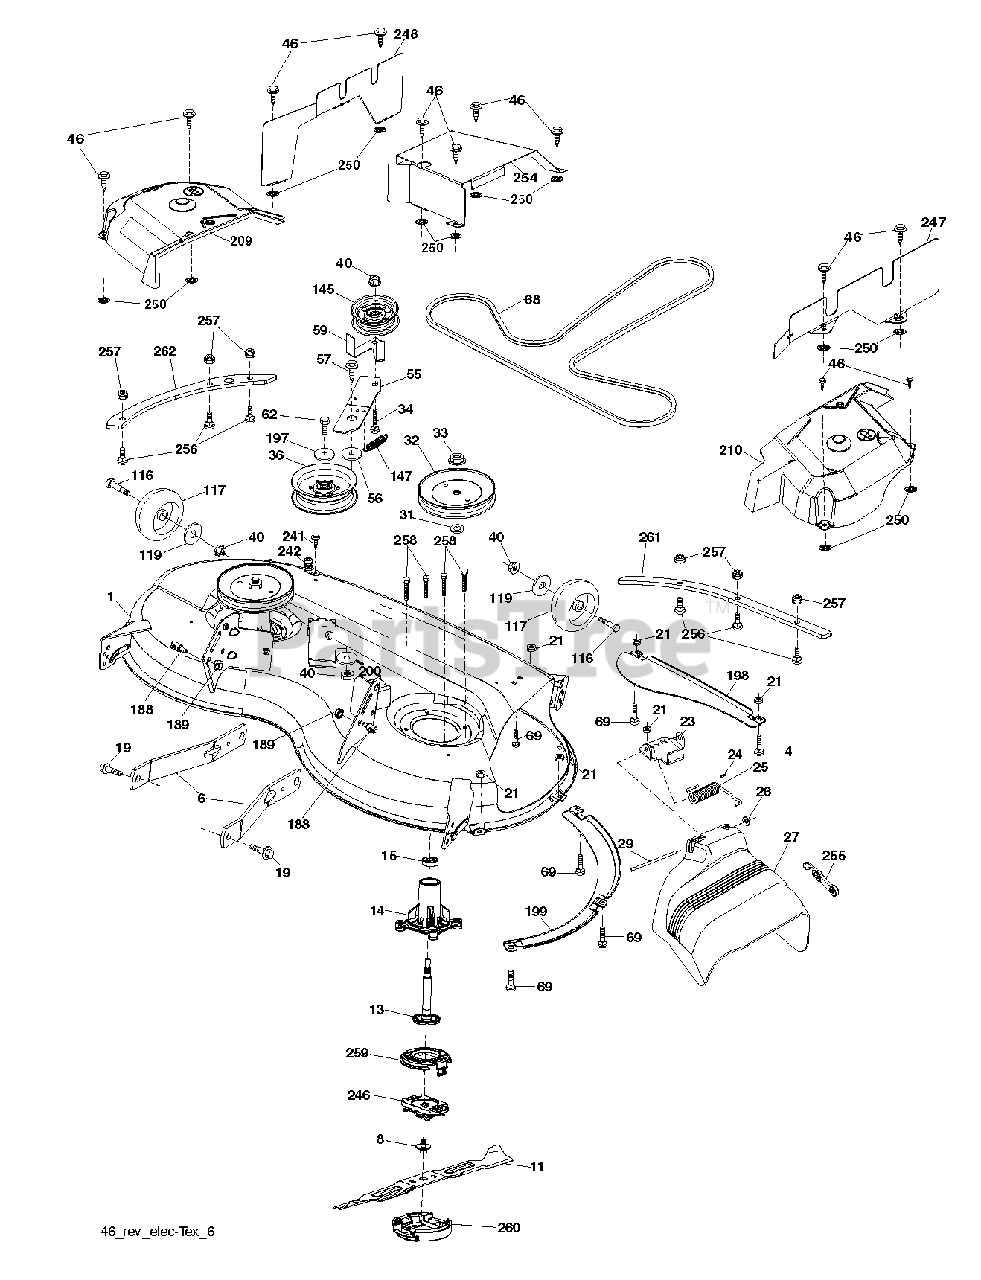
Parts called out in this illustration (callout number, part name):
1	HOUSING 46 WELDMENT TTR X498 G
4	BOLT
6	ARM.SUSPENSION.MOWER.R
8	BOLT.WASHER.ASM.7/16-2
11	BLADE.REVOLTION.46"BAGER.PT43
13	SHAFT ASM.REV.TALL.N/GREASEBL
14	HOUSING.MANDREL.REV.TALL.N/GRS
19	BOLT.SHOULDER
21	LOCKNUT
23	BRKT.DEFLECTOR.38"2005+
24	CAP-SLEEVE LT
25	SPRING.TORSION.DEFLECT
26	NUT PUSH M
27	SHIELD SUBASM DEFLECTOR 46 FRE
29	ROD.HINGE
31	WASHER.SPACER.MANDREL
32	PULLEY.MANDREL.5.438.PD
33	NUT.FLANGE.LOCK.TOP
34	BOLT.3/8-16X1.50
36	PULLEY.IDLER.2006
40	NUT LOCK FLG 3/8-16 UNC
46	SCREW.1/4-20X5/8
56	SPACER.RETAINER
57	SCREW 3/8-16X1
59	GUARD, BELT
62	BOLT-HEX EAK
68	V-BELT
69	BOLT
116	BOLT.SHOULDER.3/8-16X3-5/8.
117	WHEEL. GUAGE RALLY
119	WASHER
145	PULLEY.IDLER.48"PRIMARY
147	SPRING.MOWER.DRIVE.ELECTRIC
188	STUD.FASTNER.W/ANTI-ROTATE
189	NUT LOCK HEX FLANGE 5/16-18
197	WASHER
198	BAFFLE CENTER FRONT
199	BAFFLE FRONT RH
200	WASHER.13/32 X 1 X 1/2.11GUARD
209	COVER MANDREL LEFT
210	COVER MANDREL RIGHT
241	SCREW.TT.#10-32X.5.3/8.FLANGE
242	PORT.WASHOUT
246	HOLDER BLADE REVOLUTION
247	SHIELD RIGHT
248	SHIELD LEFT
250	PALNUT 1/4
254	SHIELD ASSEMBLY 46 TEX REAR DE
255	ELASTIC STRAP KIT
256	SCREW.BUTTONHEAD.1/4-20X1
257	NUT T
258	BOLT.HEX.WASHR.HED.313-18X1.19
259	CAP.REVOLUTION.UPPER
260	CAP.REVOLUTION.LOWER
261	PLATE.REINFORCE.46.BOLT.ONX431
262	PLATE.REINFOR.46.SIDEBOLT.X431
